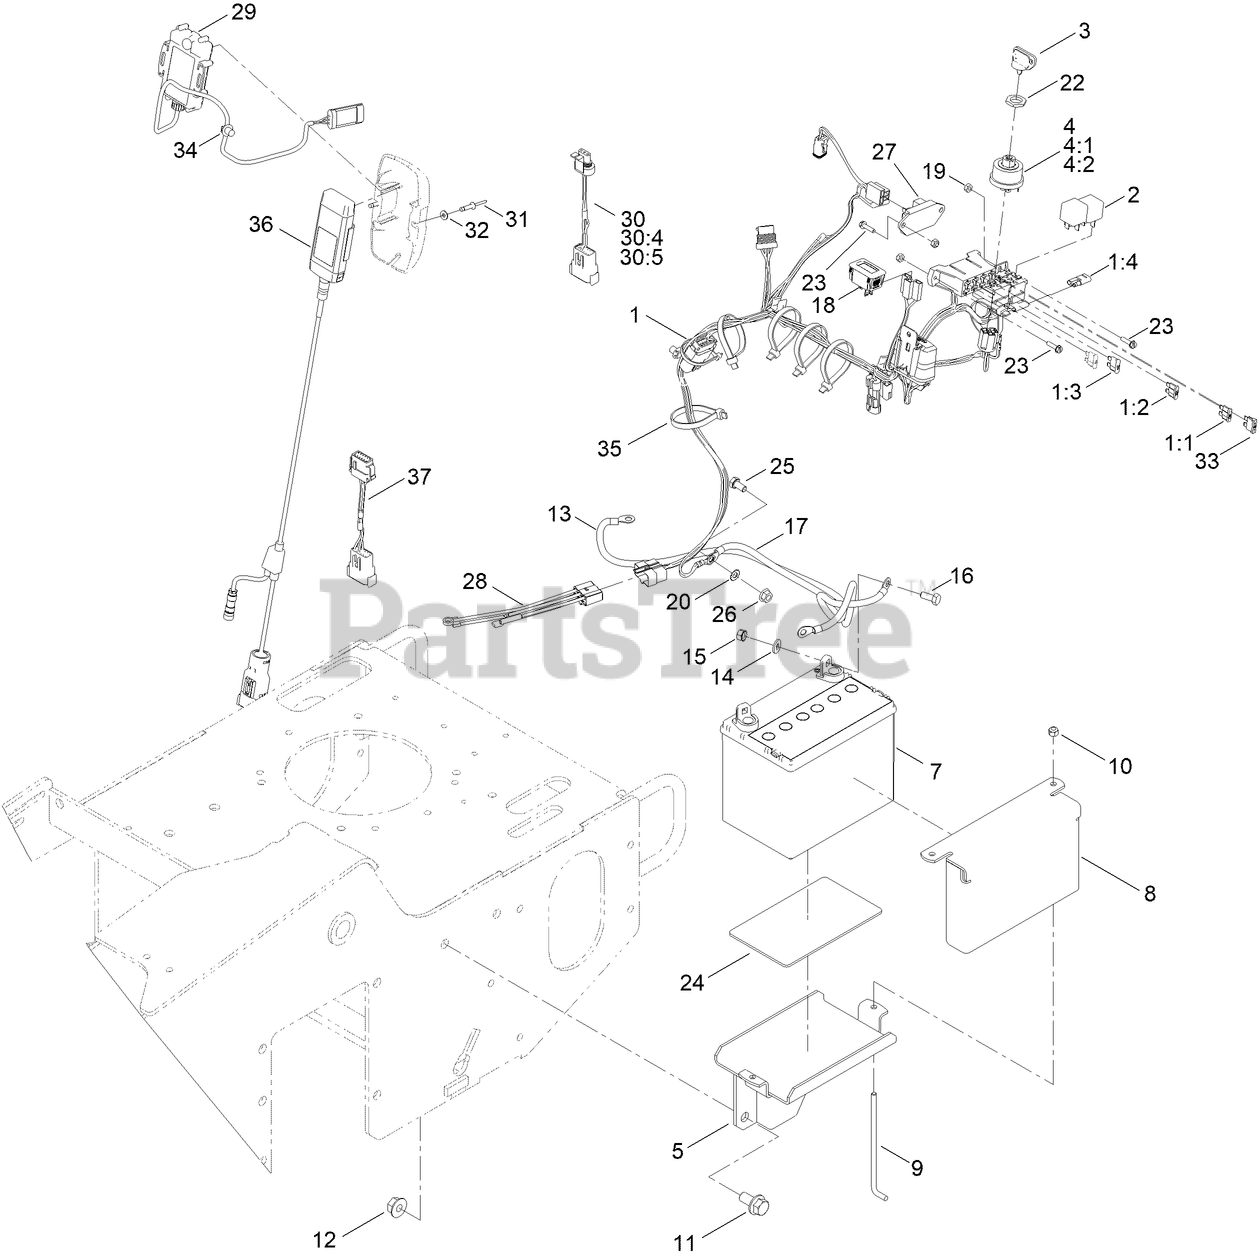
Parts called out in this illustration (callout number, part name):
1	HARNESS-WIRE
1:1	FUSE-BLADE, 30 AMP
1:2	FUSE-BLADE, 25 AMP
1:3	FUSE-BLADE, 20 AMP
1:4	CAP-PLUG
2	RELAY
3	KEY-IGNITION
4:1	WASHER-LOCK
4:2	NUT-HH
5	TRAY-BATTERY
8	PLATE-HOLD DOWN,BATTERY
9	HOLDOWN-BATTERY
10	NUT-LOCK, NI
11	SCREW-HHF
12	NUT-HHF
13	CABLE-BATTERY, POSITIVE
14	WASHER-FLAT
15	NUT-KEPS
16	SCREW-HH
17	CABLE-BATTERY, BLACK
18	HOURMETER
19	NUT-LOCK, NI
20	WASHER-LOCK
23	SCREW-HWH
24	PAD-SKID, ANTI
25	SCREW-HH
26	NUT-HF
27	MODULE-DELAY
28	HARNESS
29	GPS ASM
30	HARNESS-WIRE, GPS
30:4	FUSE-MINI BLADE, 5 AMP
30:5	COVER-FUSE, SINGLE
31	RIVET-POP
32	WASHER-PLAIN
33	FUSE-BLADE, 15 AMP
34	CLIP-TIE
35	TIE-CABLE
36	M7L-LITE ZTR KIT ASM
37	HARNESS-WIRE, MACHINE ZTR
